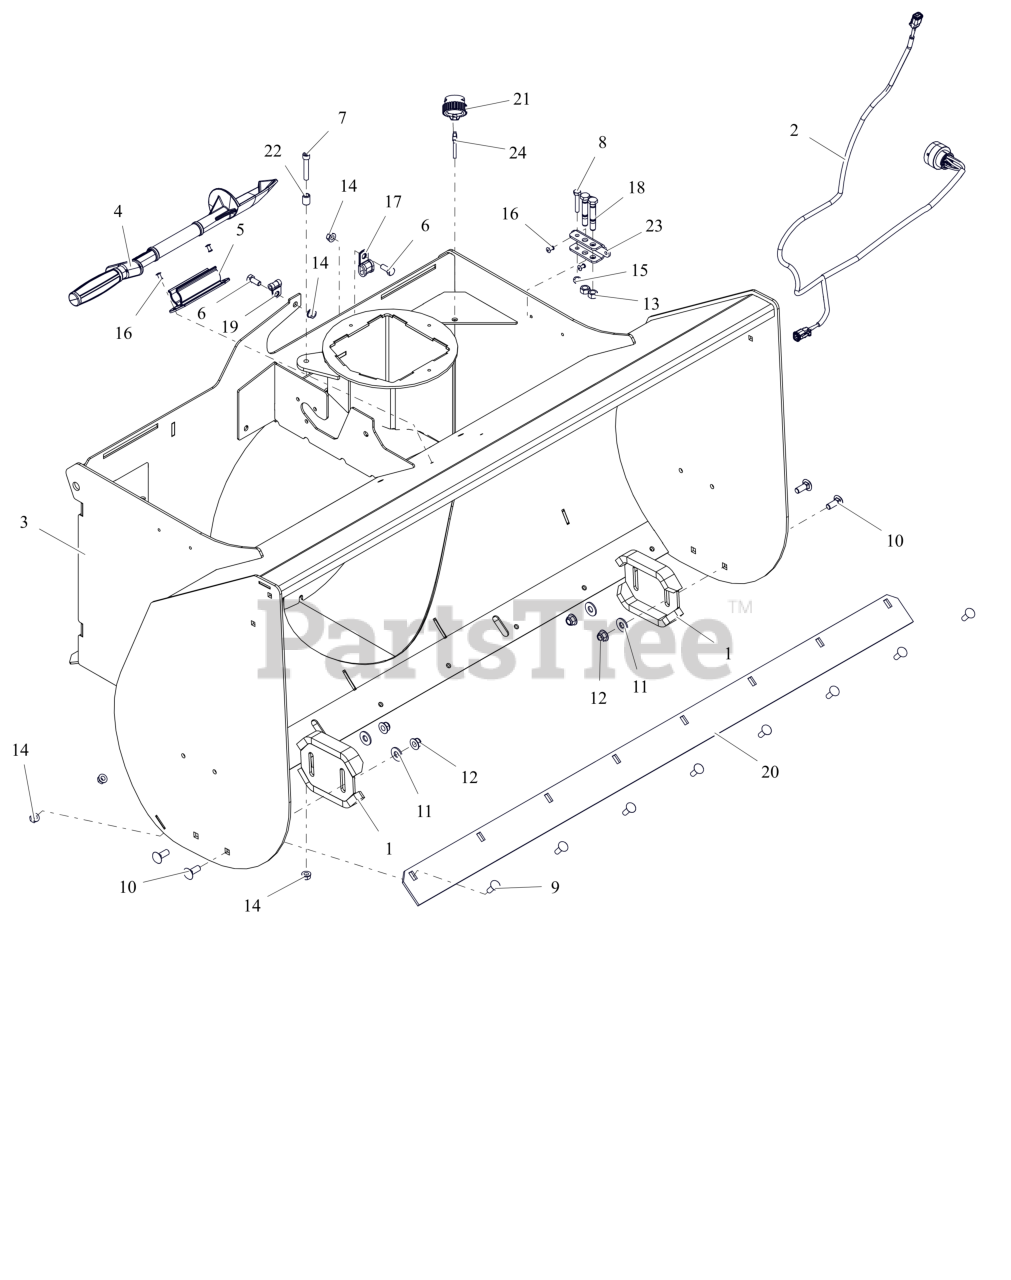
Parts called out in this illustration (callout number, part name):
1	RUNNER, SKID SHOE
2	HARNESS, BLOWER
3	WLDMT, HOUSING 48" - W/DECAL
4	DEVICE, SNOW CLEAN OUT
5	MOUNT, SNOW CLEAN OUT
6	BLT,HEX .31-18X.75 G5 ZCC
7	SCR, SKH .312-18X1.750 GR8 ZC120
8	BLT, HEX 0.25-28X1.5 G5 ZCC
9	BLT,RHSN .31-18X1.00 G5 ZCC
10	BLT, RHSN .38-16X1.00 G5 ZCC
11	WSHR,FLT .438X1.00X.083 ZCC
12	NUT,NYL-FLG .38-16 GF ZCC
13	NUT-LK-CTR .38-16 ZC120
14	NUT,LK-CTR-FLG .31-18 GF ZCC
15	NUT, NYL .25-28 ZCC
16	RVT-POP.187X.527 DOME ST
17	CLAMP, DOUBLE 5/16", 3/8" MNT
18	BOLT, SHEAR - .375-16 X 2.220
19	CLAMP, CABLE .250"
20	EDGE, CUTTING, 48" BLOWER
21	CAP, CONNECTOR - AHDC04-18
22	TUBE, ROUND .328 x .500 x .690
23	HOLDER, SHEAR BOLT - MAMMOTH
